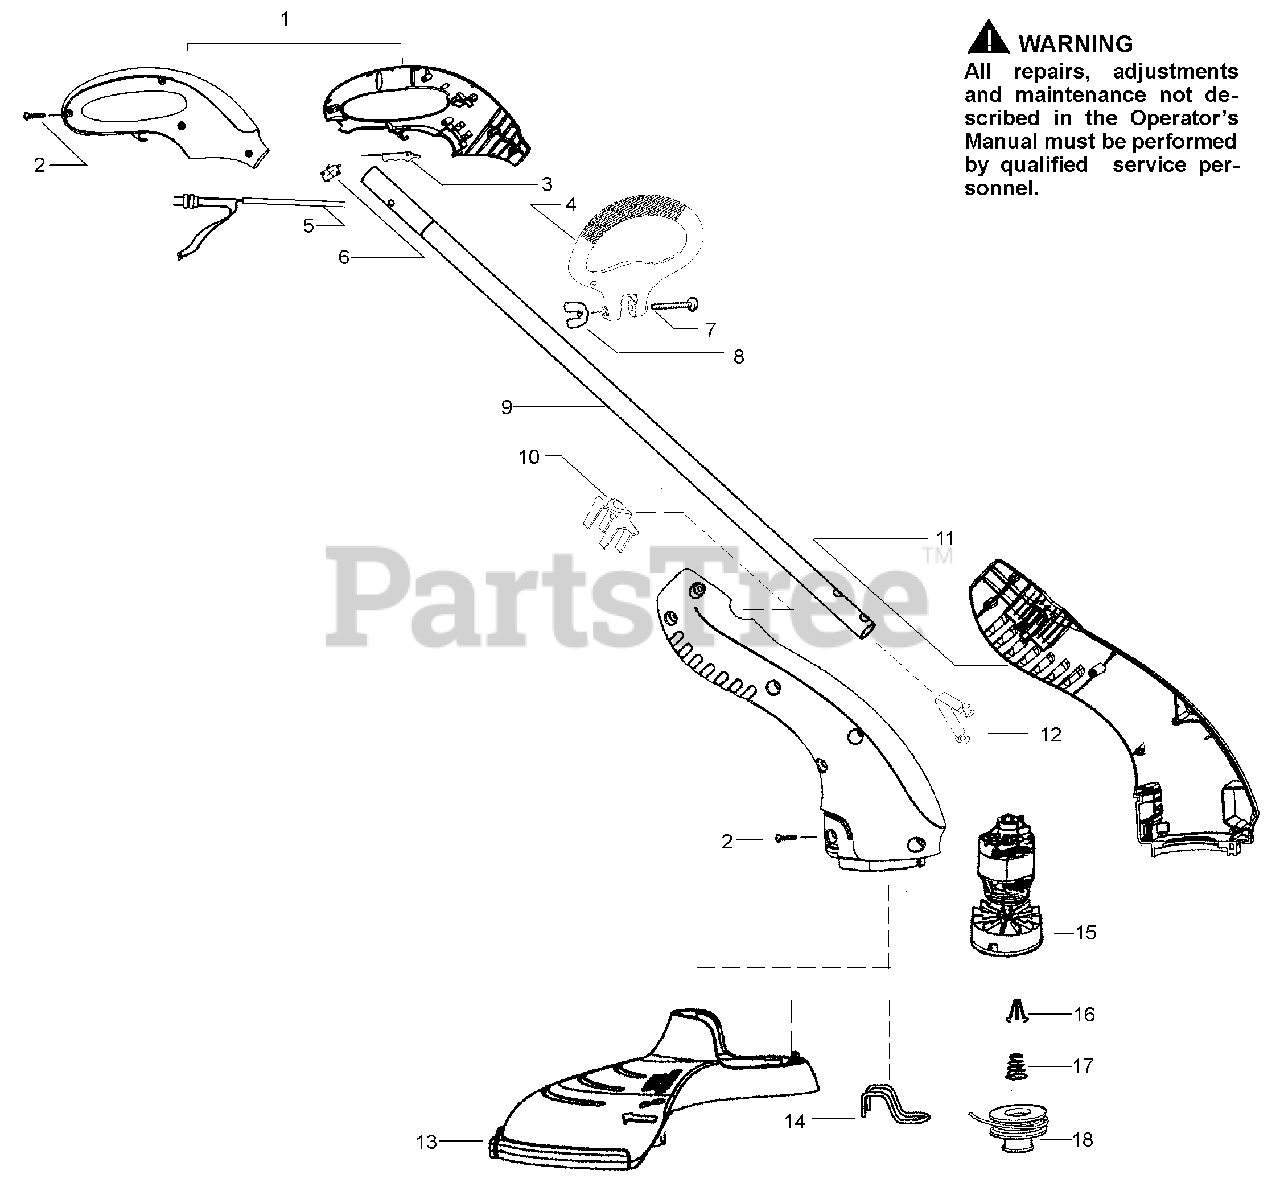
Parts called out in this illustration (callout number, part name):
1	Handle Set
4	Assist Handle
5	Wiring Harness Ass'y.
7	Bolt-Carriage
8	Wingnut
9	Assy-Tube w/Decal
10	Button-Push
11	Housing Set
12	Button-Snap
13	Assy-Shield
14	Guide - Edging
15	Assy.-Motor/Impeller
16	Retainer-Spool
17	Spring-Return
18	Accy-W/E Spool (TNG-V)
